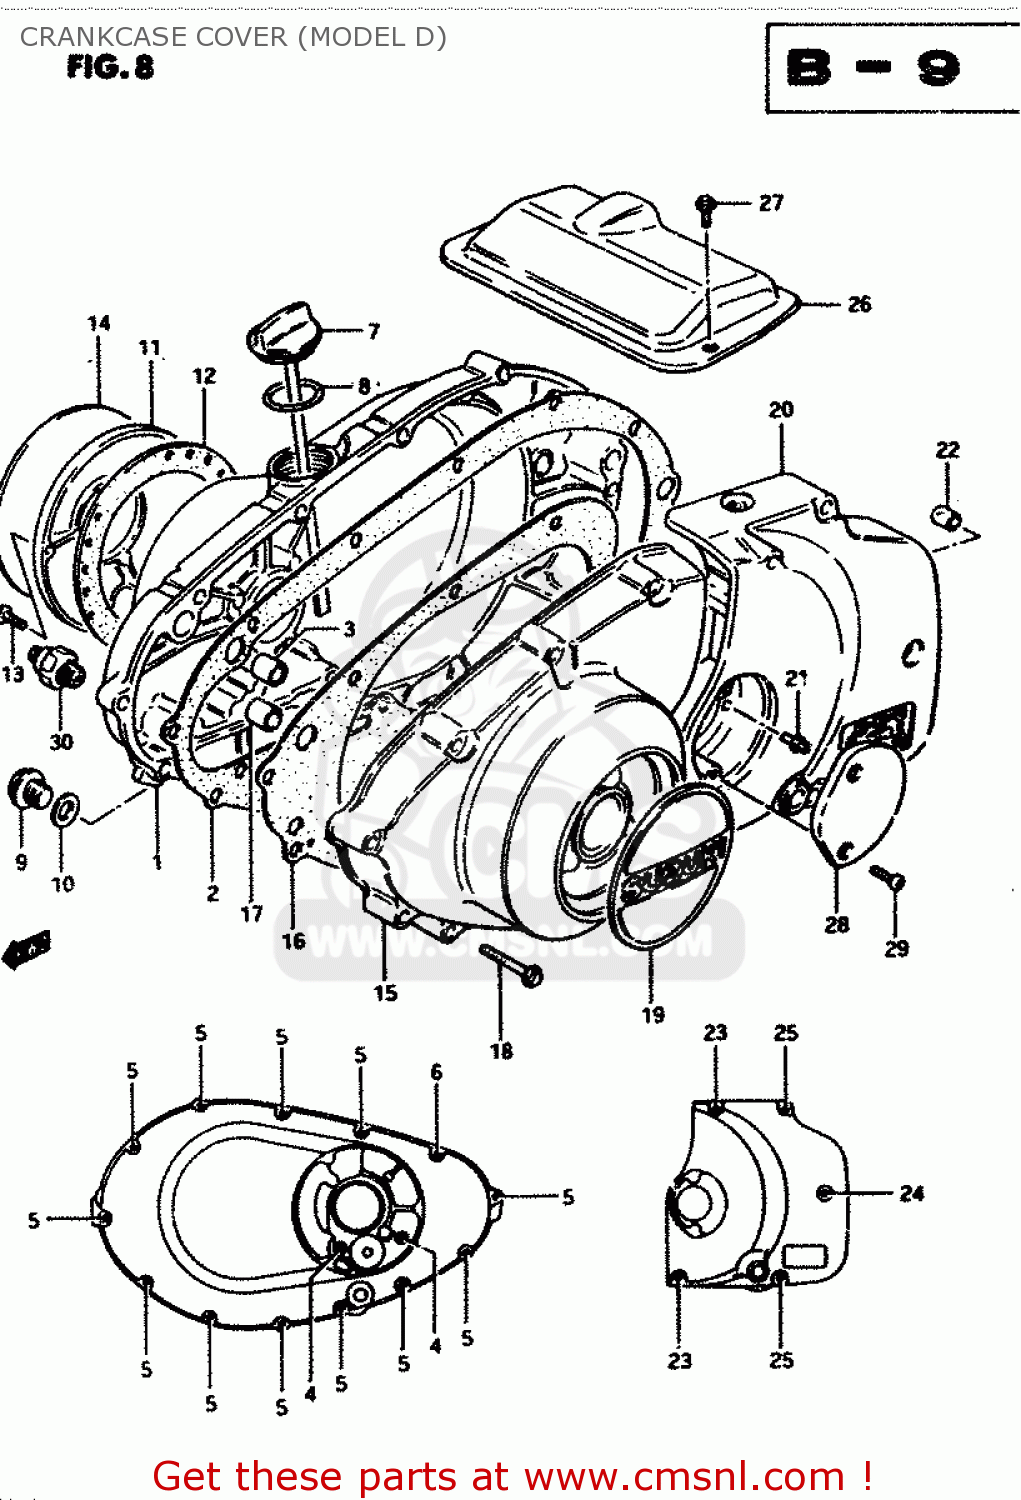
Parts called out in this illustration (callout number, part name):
1	COVER,CLUTCH
2	GASKET,CLUTCH COVER (MCA)
3	PIN
4	BOLT (6X55)
5	BOLT 6X35
6	BOLT 6X25
7	GAUGE,OIL LEVEL
8	O-RING
9	PLUG (14X12)
10	GASKET(14X19.2X2) (NAS)
11	COVER,CONTACT
12	GASKET,CONTACT (MCA)
13	BOLT 5X16
14	EMBLEM,MAGNETO COVER
15	COVER,MAGNETO
16	GASKET,MAGNETO COVER (MCA)
17	PIN
18	BOLT 6X35
19	EMBLEM,MAGNETO COVER
20	COVER, ENGINE SPROCKET
21	NIPPLE
22	PIN
23	BOLT
24	BOLT 6X50
25	BOLT 6X40
26	COVER,STARTER MOTOR
27	BOLT
28	CAP, CLUTCH RELEASE
29	SCREW
30	SWITCH ASSEMBLY
